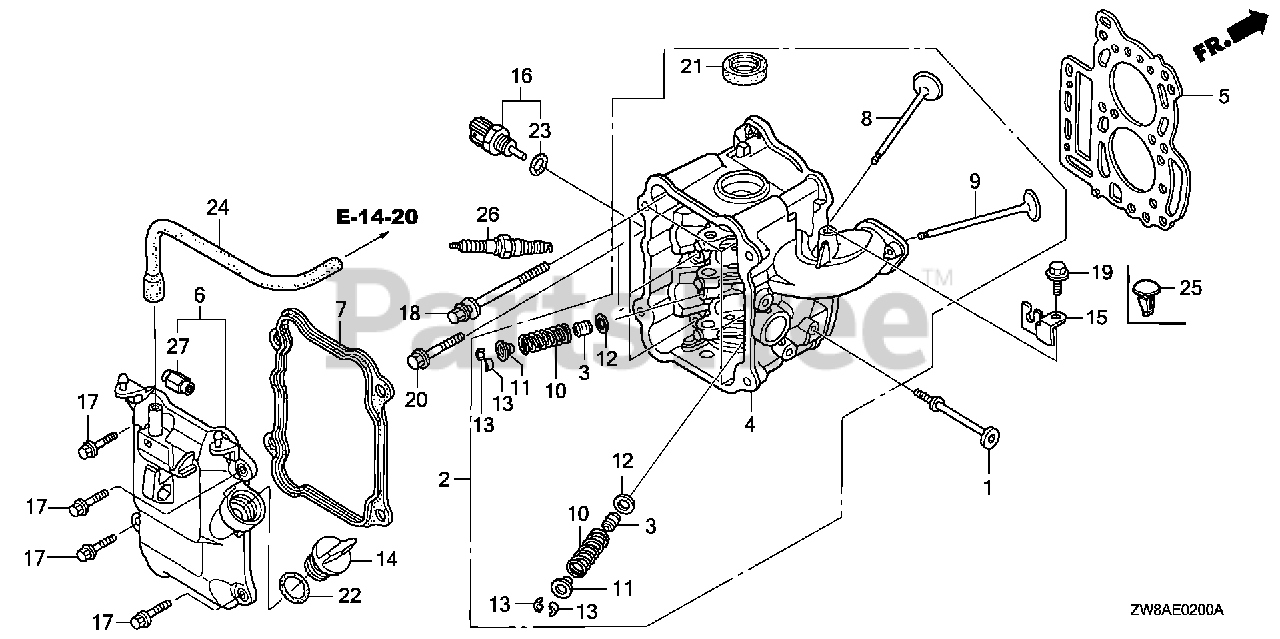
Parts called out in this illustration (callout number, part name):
1	STOPPER, ENGINE SIDE
3	SEAL, VALVE STEM (NOK)
4	CYLINDER HEAD *NH8* (DARK GRAY)
5	GASKET, CYLINDER HEAD
6	COVER, HEAD
7	GASKET, HEAD COVER
8	VALVE, IN.
9	VALVE, EX.
10	SPRING, VALVE
11	RETAINER, VALVE SPRING
12	SEAT, VALVE SPRING
13	COTTER, VALVE
14	CAP, OIL (YELLOW)
15	HOLDER, CABLE
16	SENSOR ASSY., WATER TEMPERATURE
17	BOLT, FLANGE (6X22)
18	BOLT, FLANGE (8X83)
19	BOLT, FLANGE (6X14) (CT200)
20	BOLT, FLANGE (8X40)
21	OIL SEAL (20X32X6)
22	O-RING (26X2.7)
23	O-RING (9.5X1.5) (HONDA KIKAKI)
24	TUBE, BREATHER
26	SPARK PLUG (CR5EH-9)
26	SPARK PLUG (U16FER9)
27	NUT, INSERT
